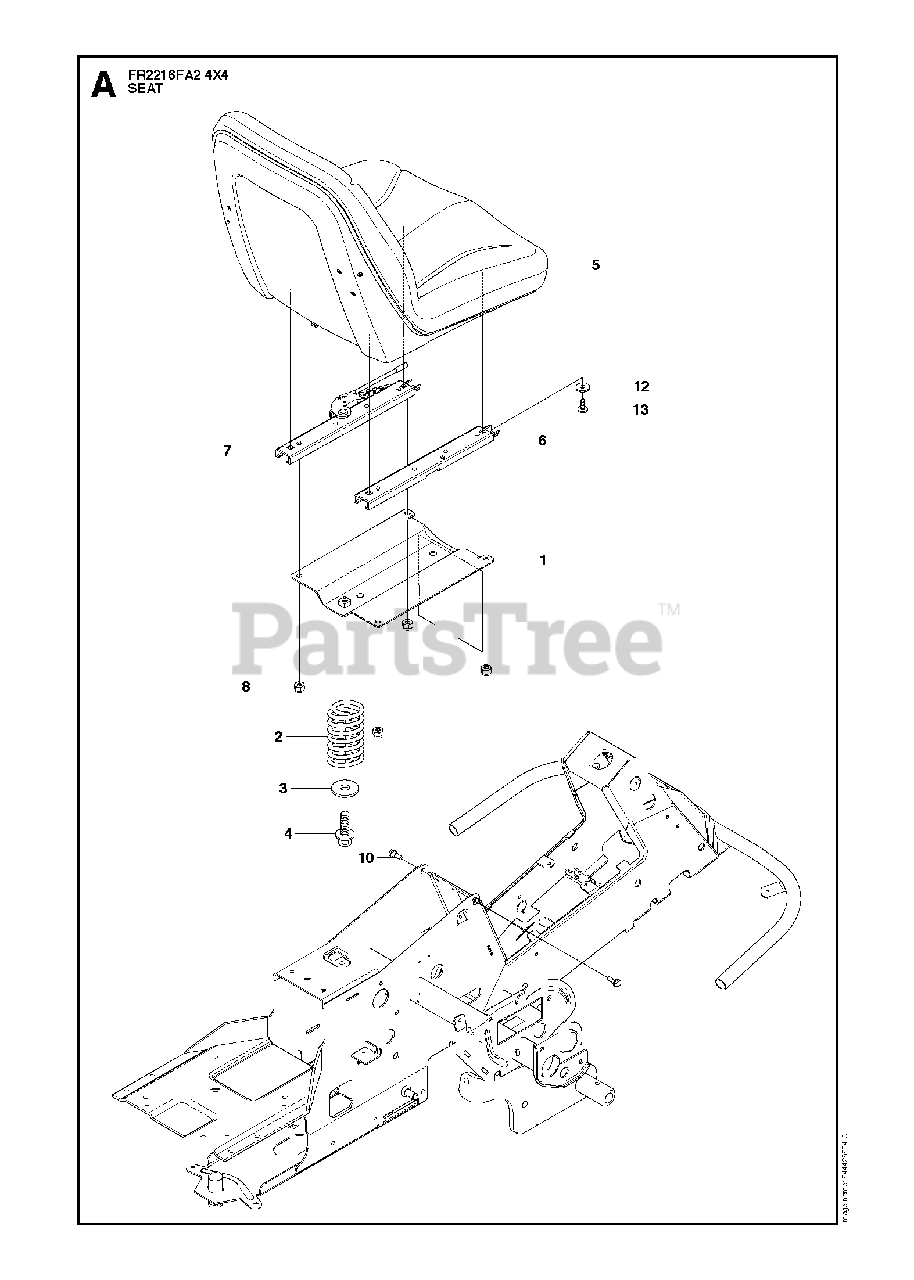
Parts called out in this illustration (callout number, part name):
2	SEAT SPRING
4	SCREW M10X25
8	LOCKNUT M8
12	WASHER
13	BOLT
